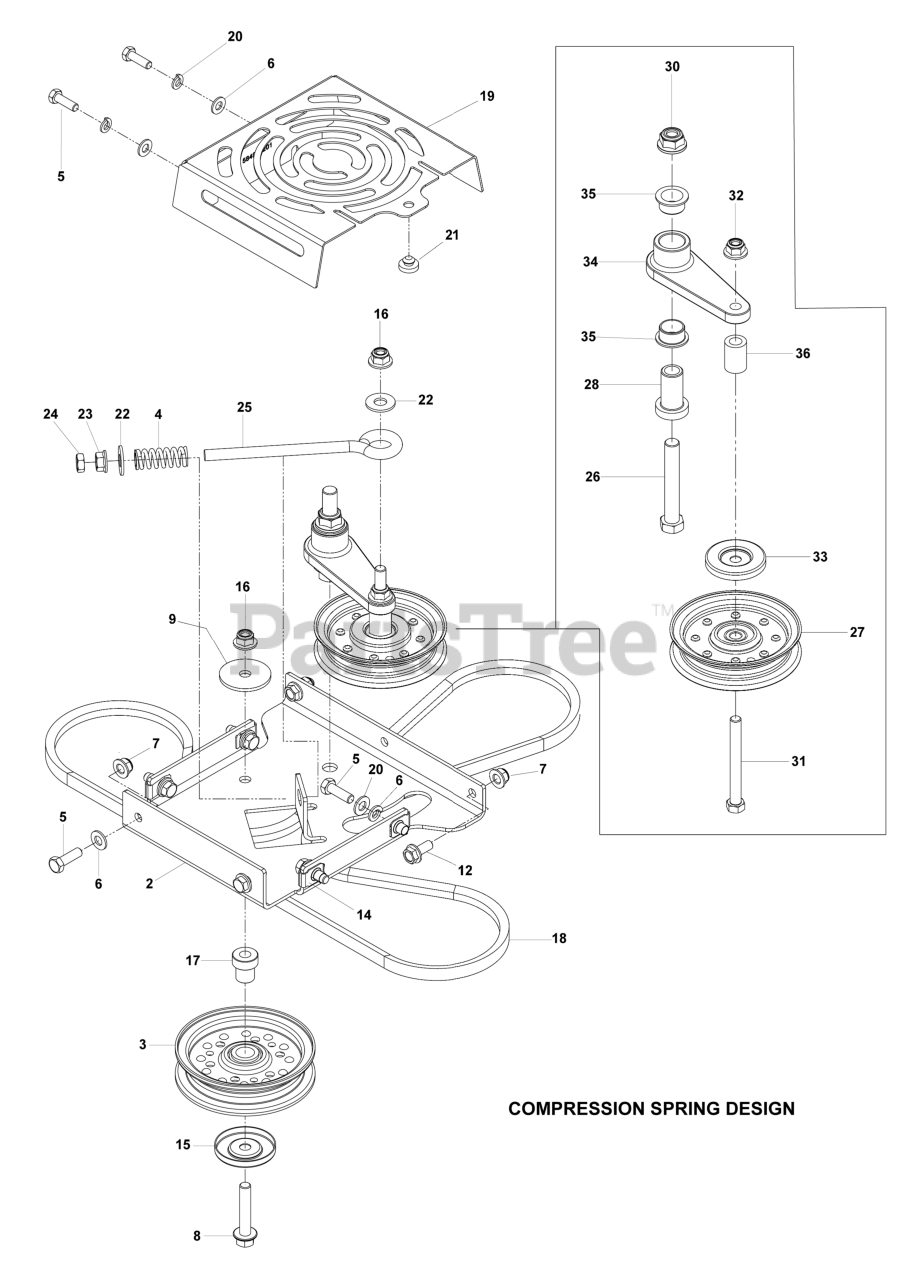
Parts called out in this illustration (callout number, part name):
2	PLATE IDLER SUPPORT BLACK X431
4	SPRING, BRAKE ROD
6	WASHER 11/32 X 11/16 X 14 GA T
7	NUT HEXAGON FLANGE 5/16-18 ST
14	U-CLIP 5/16-18 NUT RETAINER
15	SHIELD DUST
17	PIVOT, IDLER
18	BELT, HYDRO, 3400
19	SHIELD FAN BLACK
20	WASHER SPRING LOCK WASHER WITH
21	GROMMET, BUMPER
22	GSPW Washers
24	NUT NUT.3/8-16.HEX.JAM.Z 3/8-1
25	EYE BOLT EYE BOLT 1016-1020 ST
28	SPINDLE.IDLER
30	NUT 1/2-13 HEX FLANGE NYLOK CL
33	SHIELD DUST
35	BEARING FLANGED;PLASTIC 3/4" I
36	SPACER IDLER ARM
